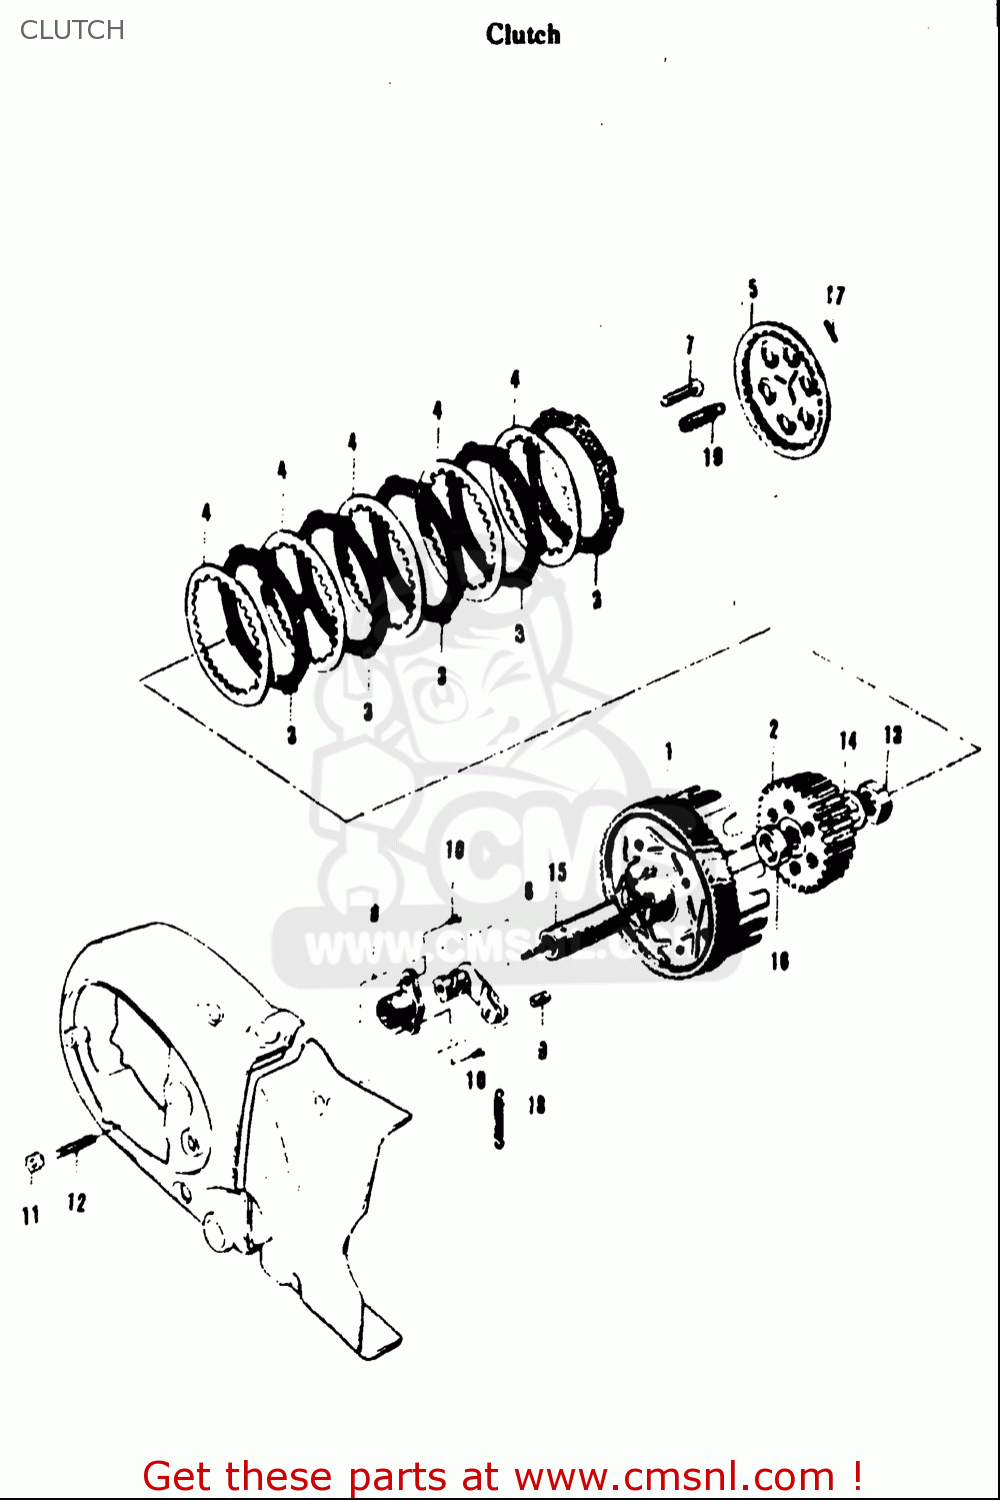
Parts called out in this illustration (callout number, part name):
3	PLATE,CLUTCH DRIVE (NAS)
4	PLATE,CLUTCH DRIVEN
6	ROD,CLUTCH PUSH
8	SCREW ASSY,CLUTCH RELEASE
9	PIECE,RELEASE ARM END
11	NUT
12	SCREW(6X25)
13	NUT
14	WASHER,LOCK
15	SPACER (17X21X52)
17	PIN(2.5X19.8)
18	SPRING
